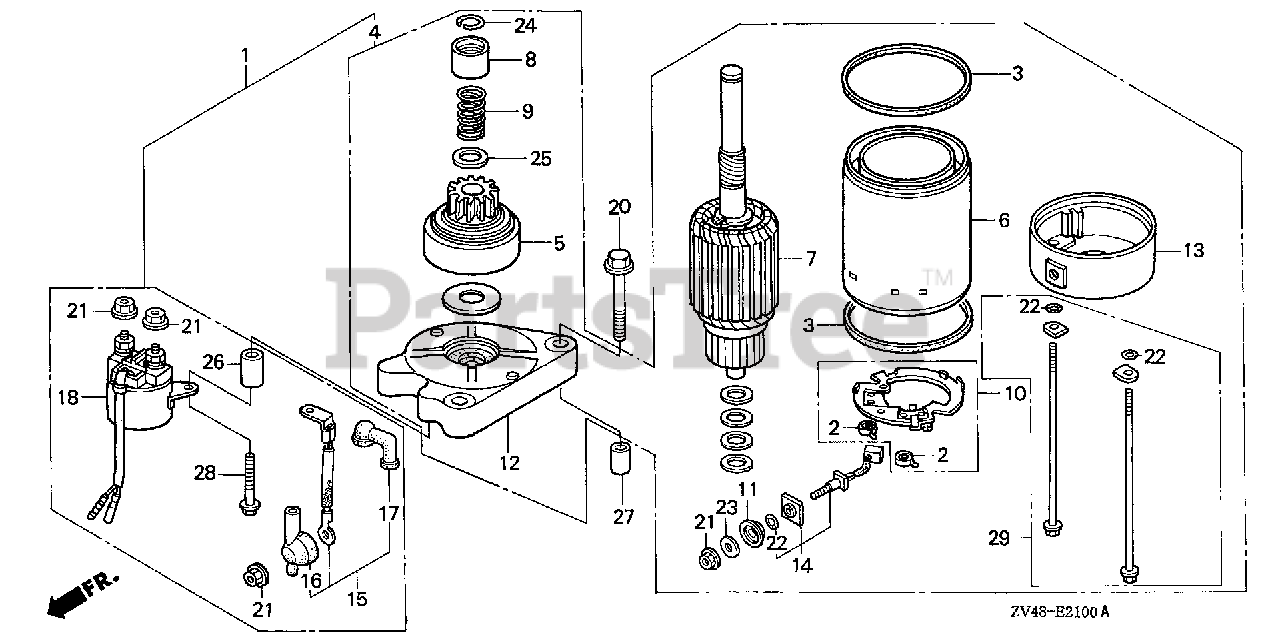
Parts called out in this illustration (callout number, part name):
1	STARTER MOTOR ASSY.
2	SPRING, CARBON BRUSH
4	STARTER MOTOR UNIT
8	PIECE, STOPPER
9	SPRING, RETURN
10	HOLDER, BRUSH
12	BRACKET, FR.
13	BRACKET, RR.
14	TERMINAL UNIT
15	WIRE, MAGNETIC SWITCH
16	COVER, STARTER TERMINAL
17	COVER, MAGNETIC SWITCH TERMINAL
18	SWITCH ASSY., STARTER MAGNETIC
20	BOLT, FLANGE (8X45)
21	NUT-WASHER (6MM)
22	O-RING (4X2)
23	WASHER (6MM)
24	CIRCLIP (14MM)
26	COLLAR, DISTANCE
27	PIN, DOWEL (10X16)
28	BOLT, FLANGE (6X32)
29	BOLT SET, SETTING
